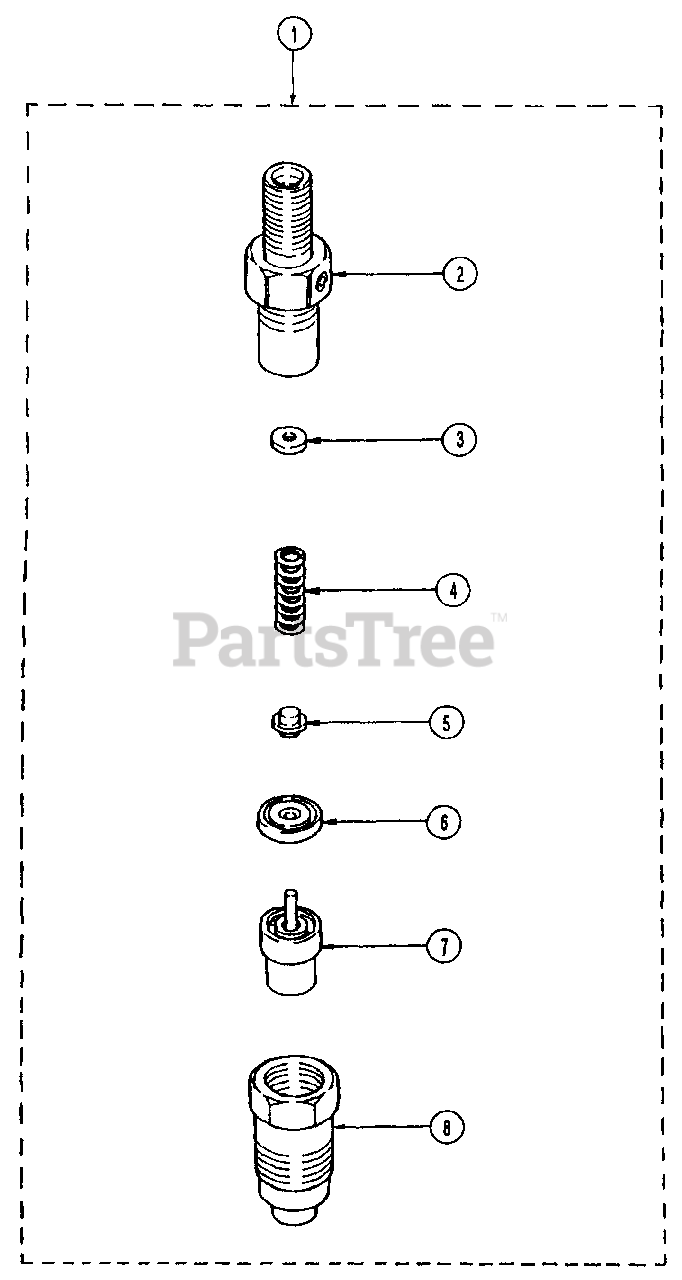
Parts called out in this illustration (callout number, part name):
1	Nozzle & Holder Ass'y.
2	Body Sub Ass'y
3	Washer T=1.25
4	Spring, Pressure
5	Pin, Pressure
6	Piece, Distance
8	Nut, Retaining
